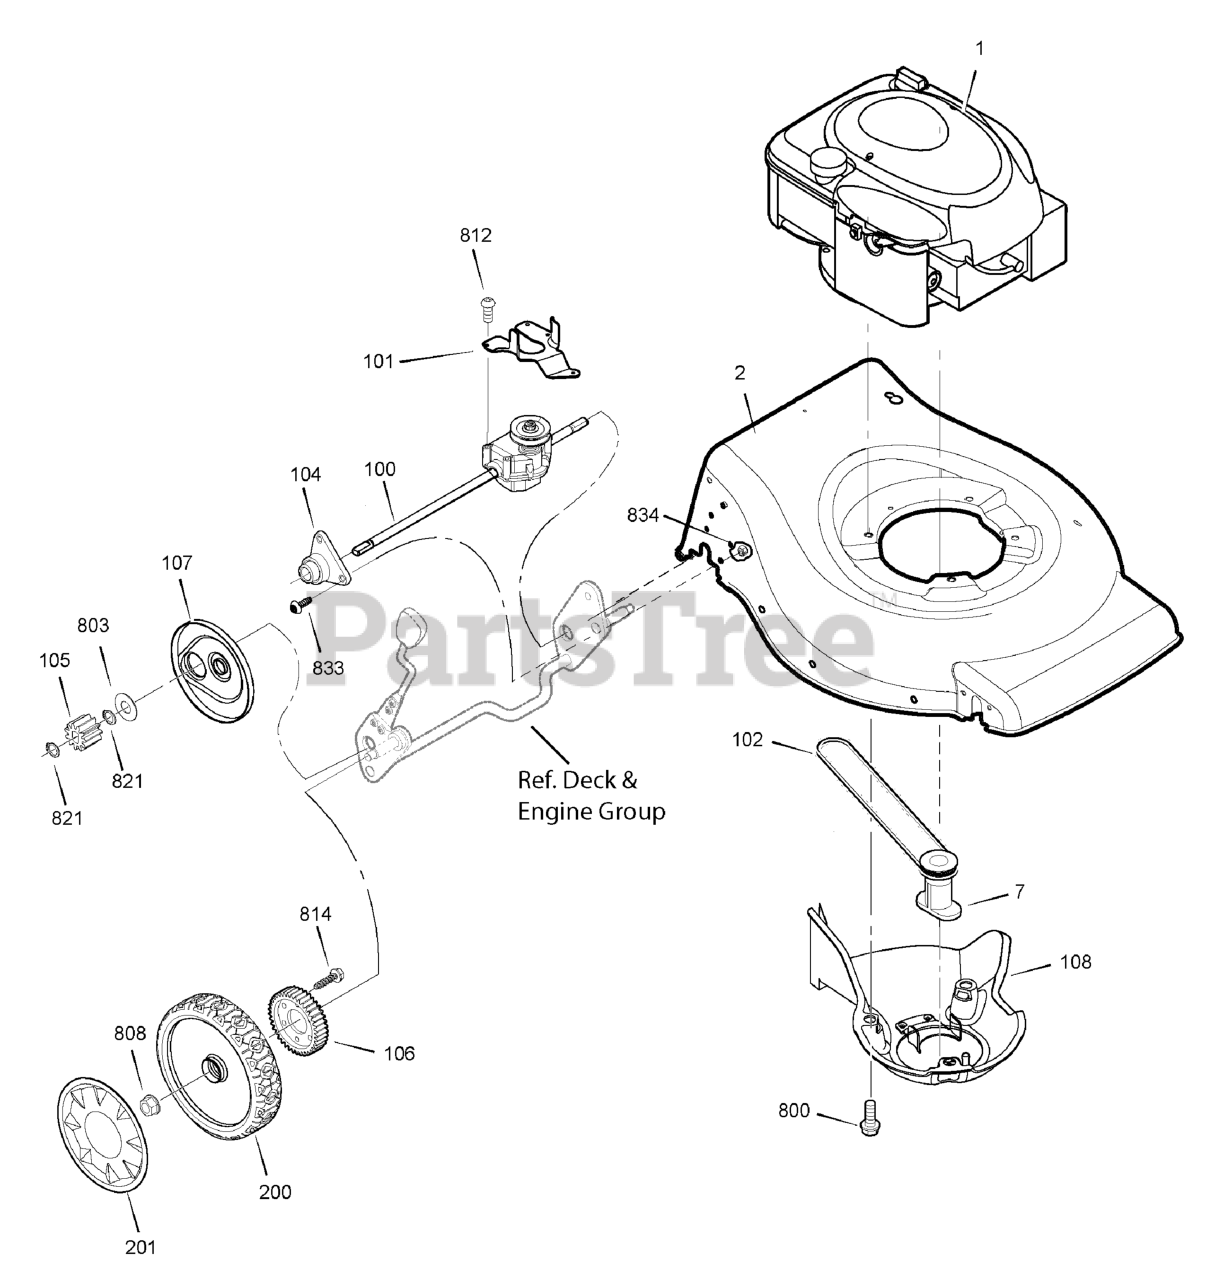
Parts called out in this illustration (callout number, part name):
1	* ENGINE
2	MOWER HOUSING
7	BLADE ADAPTER ASSEMBLY
100	TRANSMISSION
101	BELT GUIDE, Transmission
102	V-BELT
104	SLEEVE ASSEMBLY, Rear Axle
105	GEAR, Pinion
106	GEAR, Drive
107	DUST COVER
108	BELT COVER ASSEMBLY
200	WHEEL, Rear
201	HUBCAP, Rear
800	SCREW, Hex Head, 3/8-16 x 1
803	WASHER, Thrust
808	NUT, Flange, 3/8-16
812	SCREW, #10 x 1
814	SCREW, 1/4-15 x 3/4
821	RING, External Retaining
822	NUT, Hex, 1/4-20
833	SCREW, Torx, 1/4-20 x 5/8
834	NUT, Flange Lock, 1/4-20
